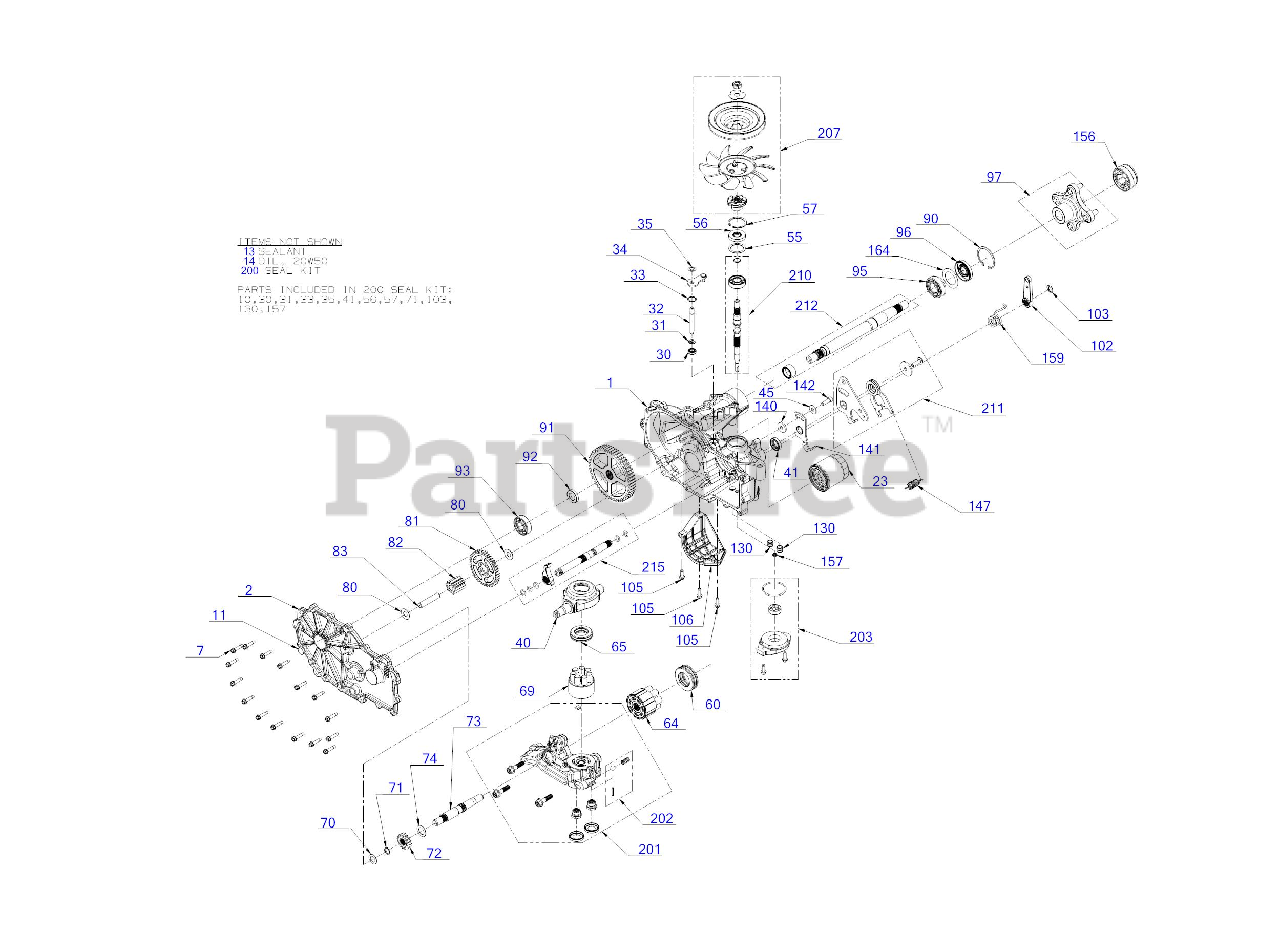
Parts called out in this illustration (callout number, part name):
1	HOUSING KIT-MAIN L
2	COVER KIT-SIDE (LH)
7	SCREW-WASHER HEAD
11	VENT PLUG
13	SEALANT-HOUSING
23	OIL FILTER
30	SEAL-LIP .375
31	RETAINING RING
32	BYPASS RODS
33	RETAINING RING
34	ARM-BYPASS
35	RETAINING RING
40	SWASHPLATE-TRUNNION
41	LIP SEAL
45	FLAT WASHER
55	WASHER 1.23X1.56X
56	LIP SEAL
57	RETAINING RING
60	THRUST BEARING
64	CYLINDER BLOCK ASSEMBLY
65	THRUST BEARING
69	BLOCK KIT-7 PISTON
70	FLAT WASHER
71	RETAINING RING
72	GEAR-16 T
73	MOTOR SHAFT
74	MOTOR SHAFT WASHER
80	WASHER
81	GEAR-43 T
82	GEAR-11 T
83	PIN-JACKSHAFT
90	RETAINING RING
91	GEAR-54 T
92	SPACER .75X1.32X.257
93	BALL BEARING
95	BALL BEARING
96	OIL SEAL
97	HUB-4 BOLT WHEEL
102	BRAKE LEVER
103	RETAINING RING
105	SCREW
106	GUARD-FILTER (LH)
130	TUBE-CHARGE TRIPLE O-RING
140	SPACER .32 x 1.005 x .179
141	ARM-NEUTRAL (LH)
142	SCREWS KIT-RTN
147	EXTENSION SPRING
156	COVER-NUT
157	KIT-GEROTOR SEAL
159	TORSION SPRING CW
164	SPACER
200	SEAL KIT
201	SECTION ASSEMBLY-CENTER
202	KIT-CHARGE RELIEF
203	CHARGE KIT
207	KIT-FAN & PULLEY
207	FAN-7.0 (10 BLADE)
207	HUB-PULLEY
207	WASHER-SLOTTED
207	NUT-JAM
209	PULLER KIT-HUB
210	SHAFT KIT-INPUT
211	KIT - RETURN CCW
212	SHAFT KIT-AXLE
215	OUTPUT SHAFT KIT (LH)
